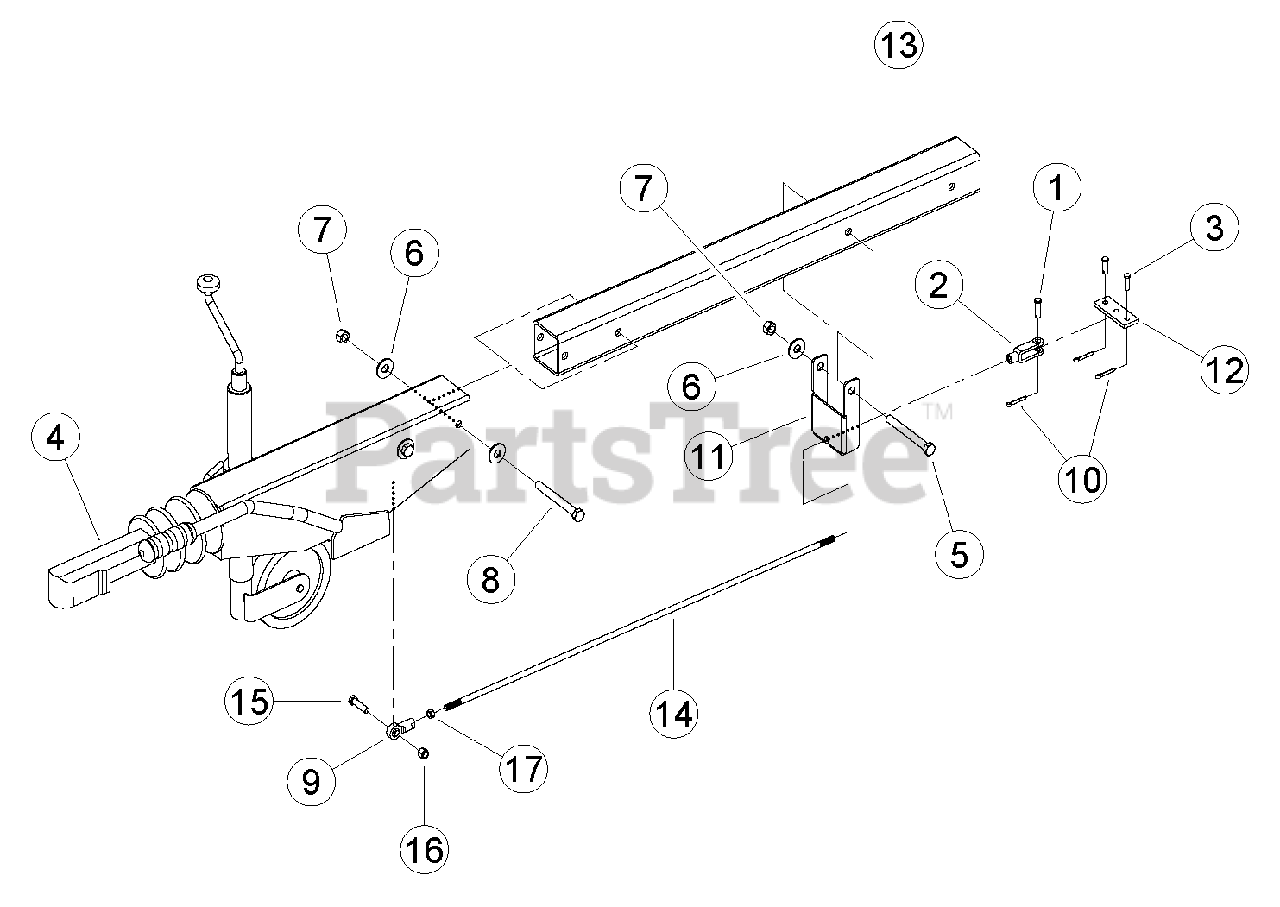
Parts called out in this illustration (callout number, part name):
1	PIN, 3/8 X 1-1/4 CLEVIS ZP
2	CLEVIS, ADJ. ROD END 3/8-24 UNF
3	PIN, 5/16 X 1 CLEVIS
4	COUPLING, SURGE W/JOCKEY WHEEL
5	BOLT, 1/2 X 4-1/2 HEX HD GR5 NC ZP
6	WASHER, 1/2 FLAT ZP
7	NUT, 1/2 CENTERLOCK GRB ZP
8	BOLT, 1/2 X 4 HEX HD GR5 ZP
9	BEARING, 3/8 ROD END
10	PIN, 1/8 X 1.00 COTTER ZP
11	BRACKET, ROD HANGER
12	BAR, BRAKE COMPENSATOR
13	TUBE, CHIPPER HITCH
14	ROD, BRAKE
15	BOLT, 3/8 X 1-1/2 HEX HD GR5 ZP
16	NUT, 3/8 NE NYLOCK ZP
17	NUT, 3/8 NFX
